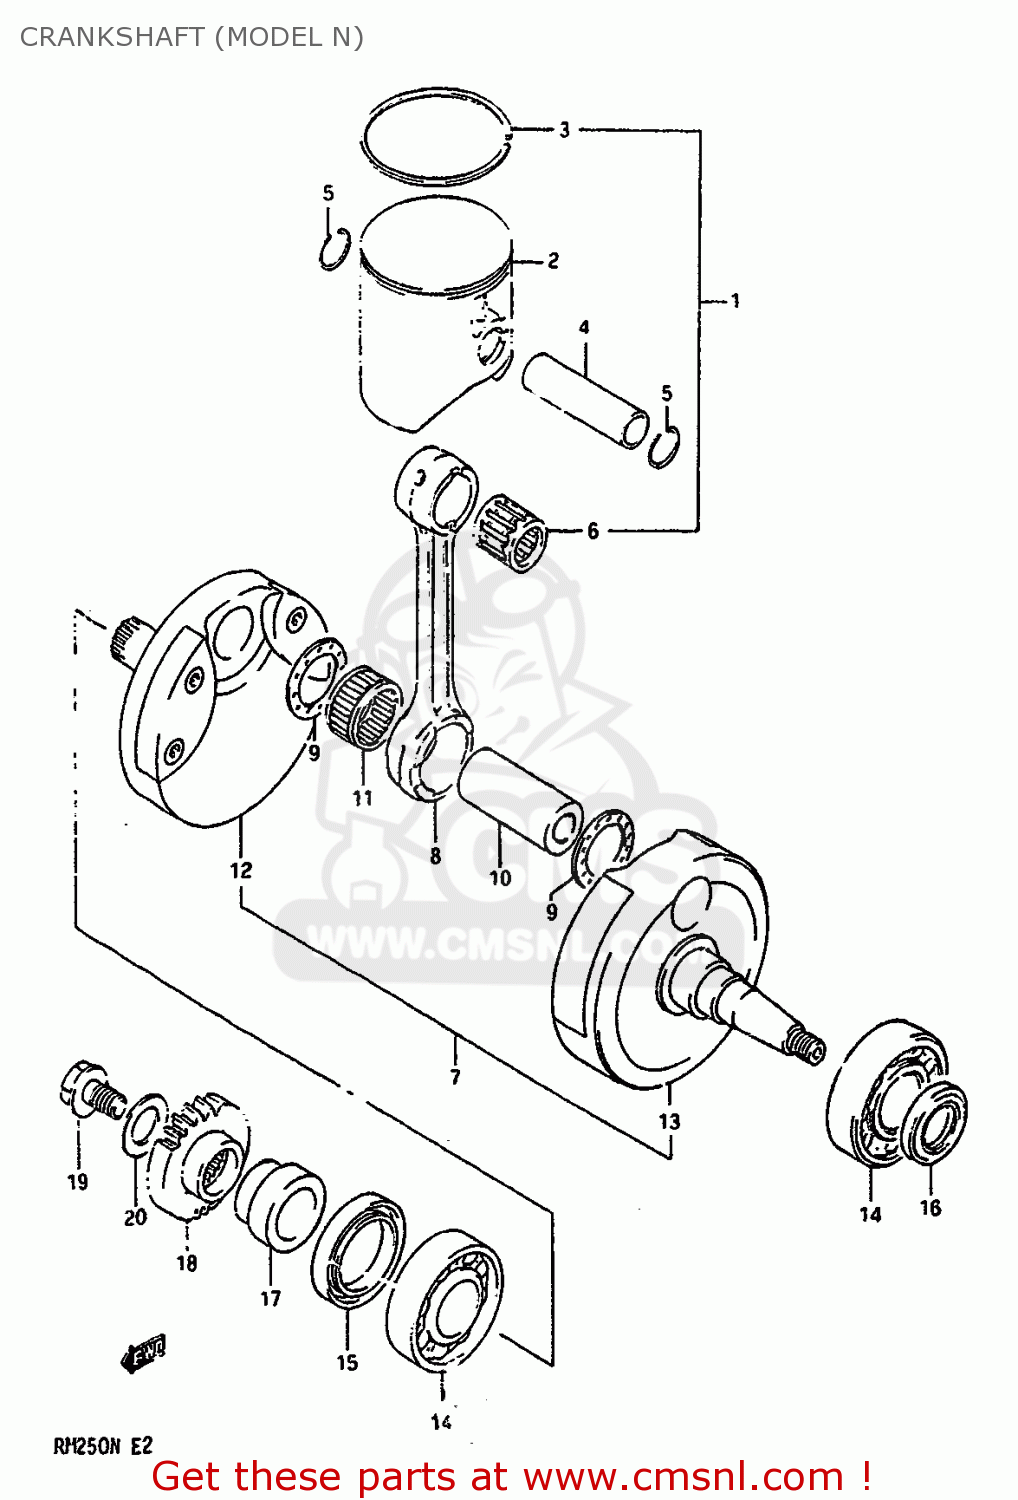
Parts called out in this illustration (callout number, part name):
1	PISTON KIT
2	PISTON
3	RING,PISTON
4	PIN,PISTON
5	CIRCLIP,PISTON PIN
6	BEARING(18X23X22)
7	CRANKSHAFT ASSEMBLY
8	ROD,CONNECTING
9	WASHER(24X38.5X1.5)
10	PIN,CRANK
11	BEARING(24X30X20)
12	CRANKSHAFT
13	CRANKSHAFT,LEFT
14	BEARING(25X62X17)
15	SEAL,OIL(36X52X7)
16	SEAL,OIL(20X37X6)
17	SPACER,PRIMARY DRIVE GEAR
18	GEAR,PRIMARY DRIVE
19	BOLT,PRIMARY DRIVE GEAR
20	WASHER
21	WASHER
